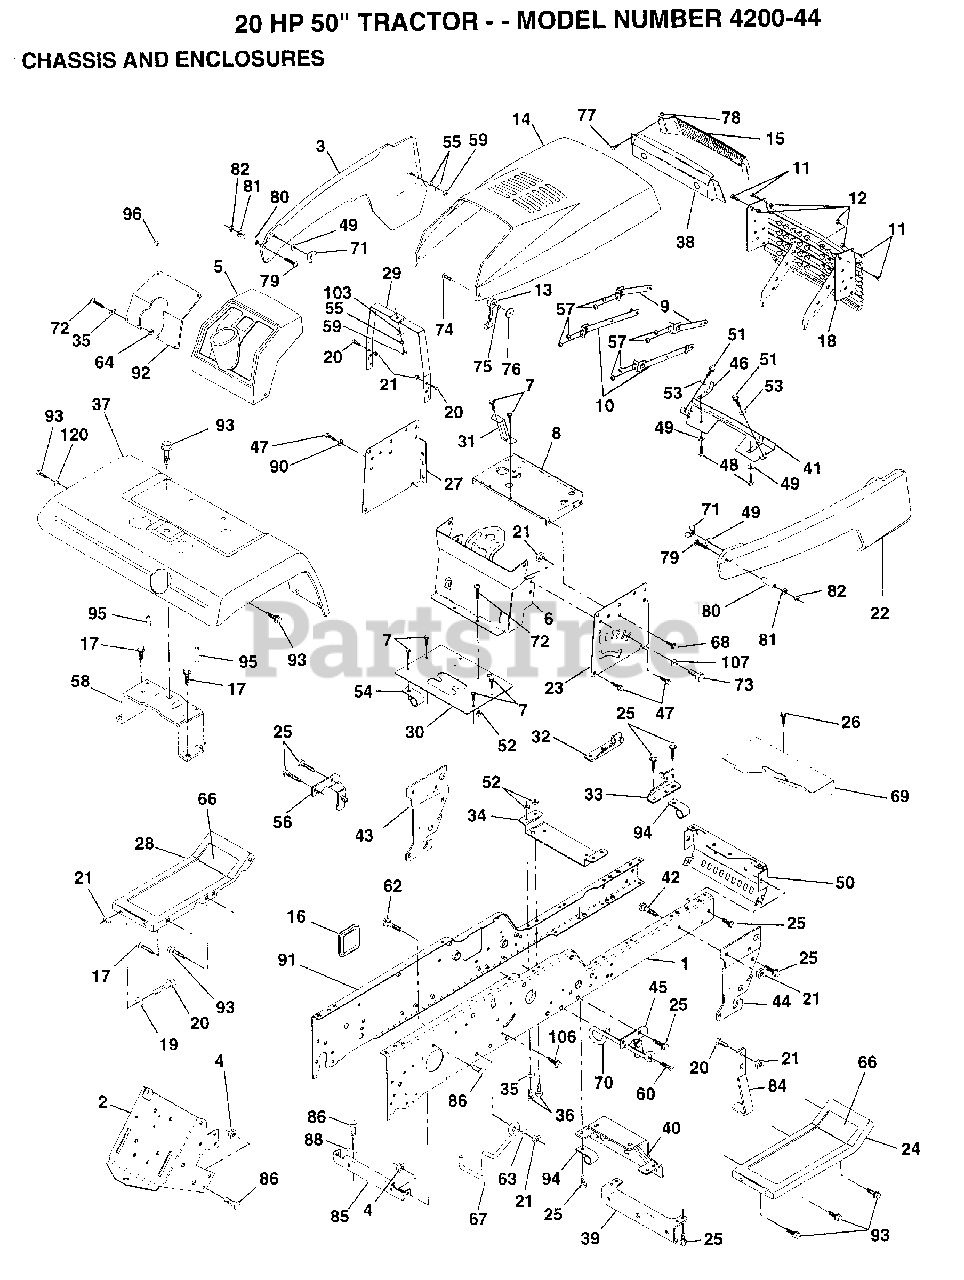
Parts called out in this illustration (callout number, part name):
2	DRAWBAR GT
3	PANEL SIDE LH
4	NUT.7/16
5	DASHBOARD BLACK
6	DASH ASM LOWER
7	SCREW
8	SUPPORT BATRY VGT
12	NUT
13	HOOD LATCH T
15	LENS LT
16	COVER ACCESS
17	SCREW
18	GRILLE.ASM.PNT.YP
19	WASHER
20	BOLT
21	NUT
25	SCREW
26	SCREW
29	SUPPORT ASS'Y
30	SADDLE SILKSCRN
31	BRACE.SUPT.STRG
32	BRACKET ASM FRAME
33	BRACKET ASM FRAME
35	WASHER
36	BOLT
39	BRACKET.AXLE.FRT.
43	BRACKET.SUS.FT.LH
44	BRACKET.SUS.FT.RH
47	SCREW LT
48	SCREW
49	WASHER
50	BRACKET.CHASSIS.
51	SCREW HEX CRT
52	NUT
53	WASHER
54	"CLIP,INSULATOR"
55	WASHER PM
57	NUT
58	BRKT.ASM.FENDER
60	SCREW
62	BOLT D
63	WASHER
66	FOOTREST PAD
67	GUIDE BELT TRANS
68	SCREW LT
69	SHIELD.HEAT.MUF
70	GUIDE.BELT.MID.SP
73	BOLT
74	SCREW
75	LOCKWASHER
76	WELDNUT
78	"""J"" FASTENER LT"
79	SCREW
80	SPACER LT
81	WASHER
84	STOP.OVER.CENTER
86	BOLT
88	LOCKWASHER
90	LOCKWASHER
92	PLATE DASH SILKSC
93	SCREW LT
94	CLIP GTV
95	NUT-PUSH YT
96	PLUG-DASH T
103	LOCKWASHER
106	BOLT.5/16-18X1.25
107	WASHER
120	WASHER HYT
